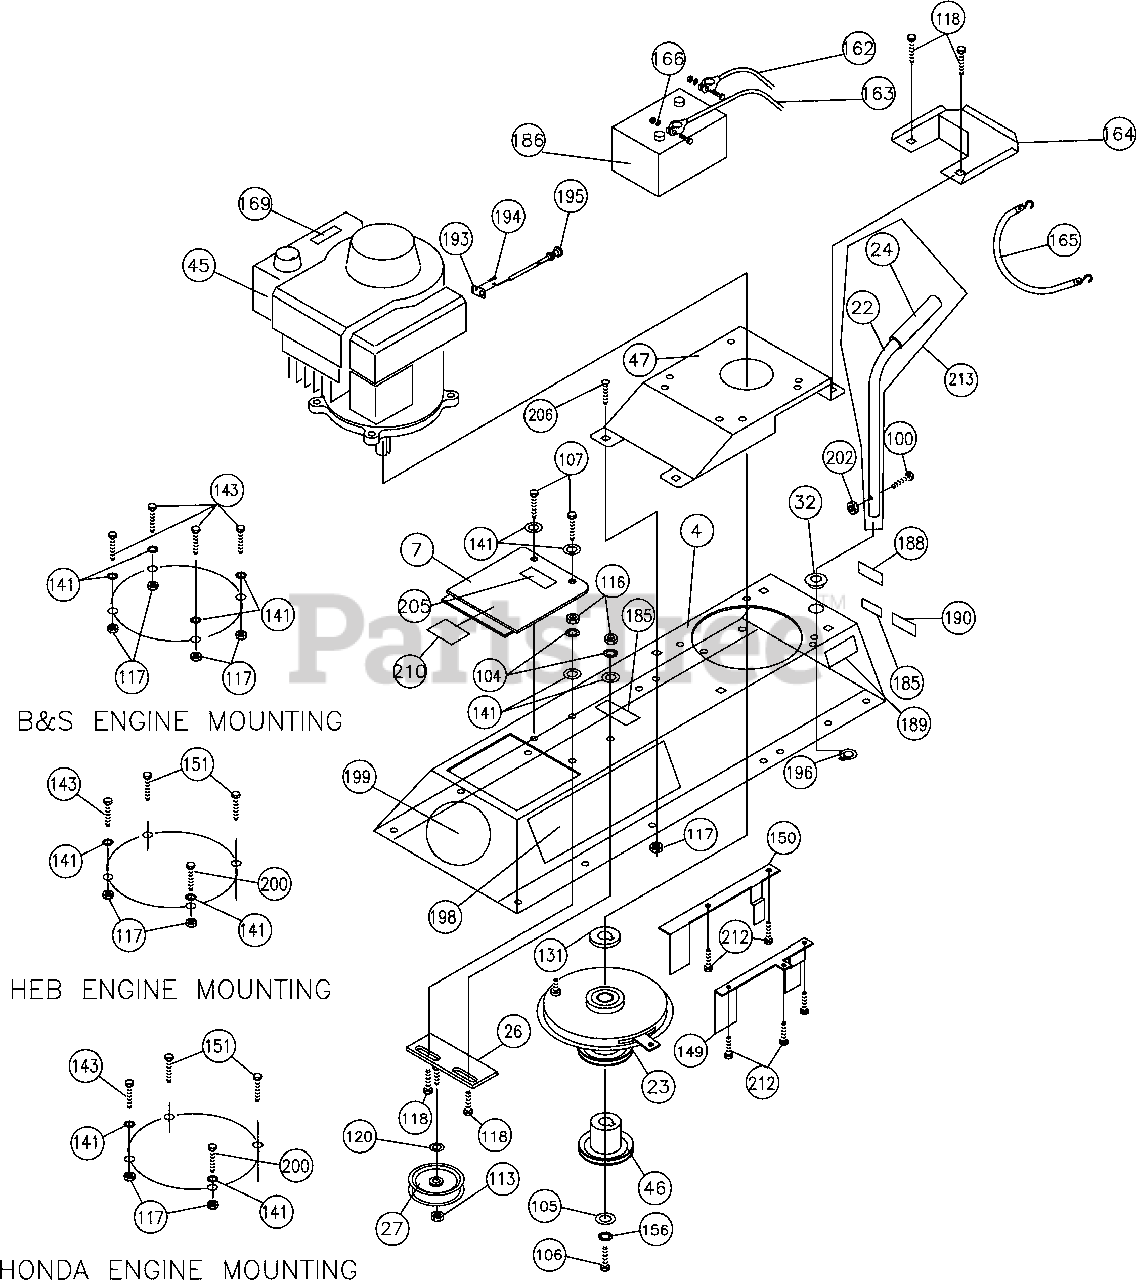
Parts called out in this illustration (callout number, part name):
4	Base Assembly with labels
7	Door Base Engine
22	Tube Shift With Grip
23	Clutch Brake
24	Grip 3/4 ID - Black
26	Plate Mount Idler WA
27	Pulley Idler 4.5" OD X 3/8”
32	Bushing Shifter
45	13 HP OHV B & S
46	Pulley Drive Traction BC
47	Spacer Engine WA 2401
100	Screw cap ¼-20 x 1 1/4
104	Washer Split Lock 5/16”
105	Plate Impeller Washer
106	Screw Cap 7/16-20 X 2 3/4"
107	Screw cap 5/16” – 18 x 1” HCS ZP
110	Part Not Applicable on this model
113	Nut Lock 3/8-16
116	Nut Jam 5/16-18
117	Nut Lock 5/16-18
118	Bolt Carriage 5/16-18 x 1”
120	Washer 3/8 FC
131	Spacer Engine
140	Part Not Applicable on this model
141	Washer 5/16” FC
143	Screw Cap 5/16-18 x 1-3/4”
149	Guide Belt LH
150	Guide Belt RH
151	Part Not Applicable on this model
156	Washer lock 7/16" ST Med
162	Part Not Applicable on this model
163	Part Not Applicable on this model
164	Part Not Applicable on this model
165	Part Not Applicable on this model
166	Washer 1/4” SAE
169	Label Fuel EN/SP
185	Label Guards
186	Part Not Applicable on this model
188	Label Ear Eye Breathe
189	Label Chock Wheels
190	Label Patent No
193	Part Not Applicable on this model
194	Part Not Applicable on this model
195	Part Not Applicable on this model
196	Ring Retaining External 3/4”
198	Label Outback BC
199	Label Product Decal
200	Part Not Applicable on this model
202	Part Not Applicable on this model
205	Label Spark Arrester
206	Carriage bolt 5/16”-18 x ¾” ZP
210	Label Made in U.S.A
212	Screwcap 5/16”-18 x 3/4”
